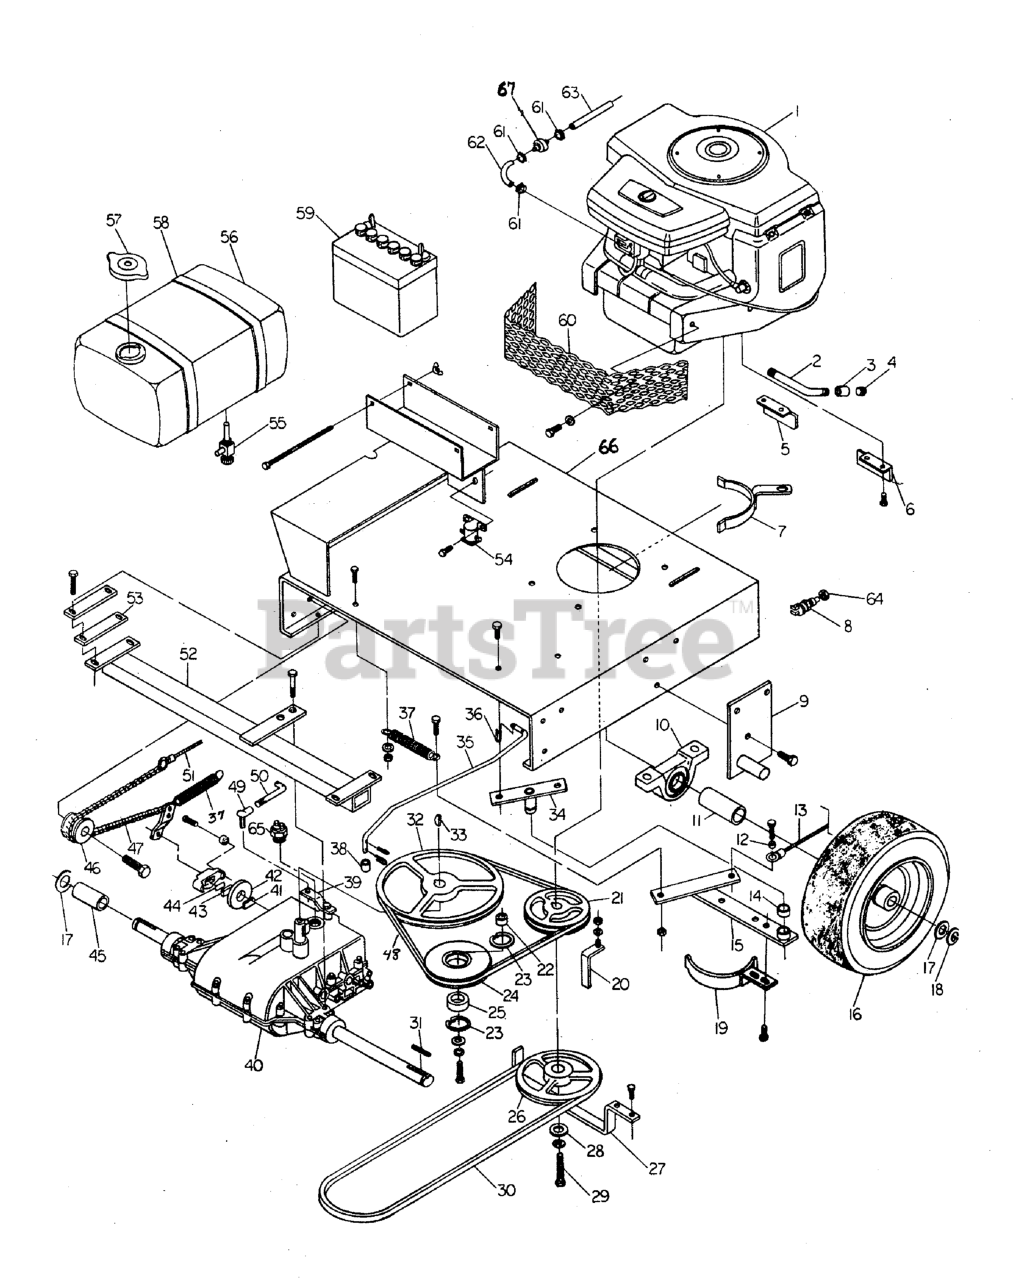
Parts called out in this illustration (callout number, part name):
1	ENGINE, 18HP Briggs & Stratton
2	Oil Drain Extension
3	Coupler
4	Pipe Plug
5	Heat Shield Right
6	Heat Shield Left
7	ENGINE BELT GUIDE
8	Safety Switch
9	Pivot Bracket - LH
10	Pillow Block Bearing
11	SPACER, .76 x 1.00 x 3.38
12	Cable Spacer
13	Clutch Cable
14	BUSHING, Brass
15	Idler Arm Weldment
16	Drive Tire Assembly (Tire & Rim)
16	Tire Only
16	Rim Only
16	DRIVE HUB
17	SHIM
18	C-CLIP
19	Idler Pulley Belt Guide
20	Belt Guide
21	ENGINE PULLEY
22	INSERT, Bearing
23	SNAP RING, Internal
24	Idler Pulley Clutch
25	BEARING, BALL 11/16X1-9/16X15/32
26	ENGINE PULLEY
27	Belt Guide
28	SPACER, .44 X .75 X .63
29	BOLT, 7-16-20 x 1-1/2
30	BELT, B Section
31	KEY, 3/16" SQ. X 2-1/2
32	Transaxle Pulley
33	KEY, #9 Woodruff
34	Idler Pivot Weldment
35	Linkage Arm
36	HAIRPIN CLIP
37	SPRING, Extension
38	SLEEVE
39	Shifting Lever
40	Transaxle
41	Brake Pad
42	Brake Disc
43	Brake Pad
44	Brake Pad Plate
45	SPACER, .76 x 1.00 x 1.88
46	Beveled Idler Block
47	CHAIN, #41 Roller, 43 Links
48	Belt A Section
49	BALL JOINT, 3/8" Female Studded
50	Shifting Linkage
51	Brake Cable
52	Transaxle Support Weldment
53	Transaxle Support Spacer
54	SOLENOID, Starter
55	Needle Valve
56	Fuel Tank, 4 Gallon
57	Gas Cap
58	Gas Tank Strap
59	BATTERY, 11U1L, 350 CCA
60	Muffler Guard
61	CLAMP, Hose
62	Fuel Hose Short
63	Fuel Hose Long
64	Brass Nut
65	Neutral Safety Switch
66	Engine Deck Weldment
67	Fuel Filter
